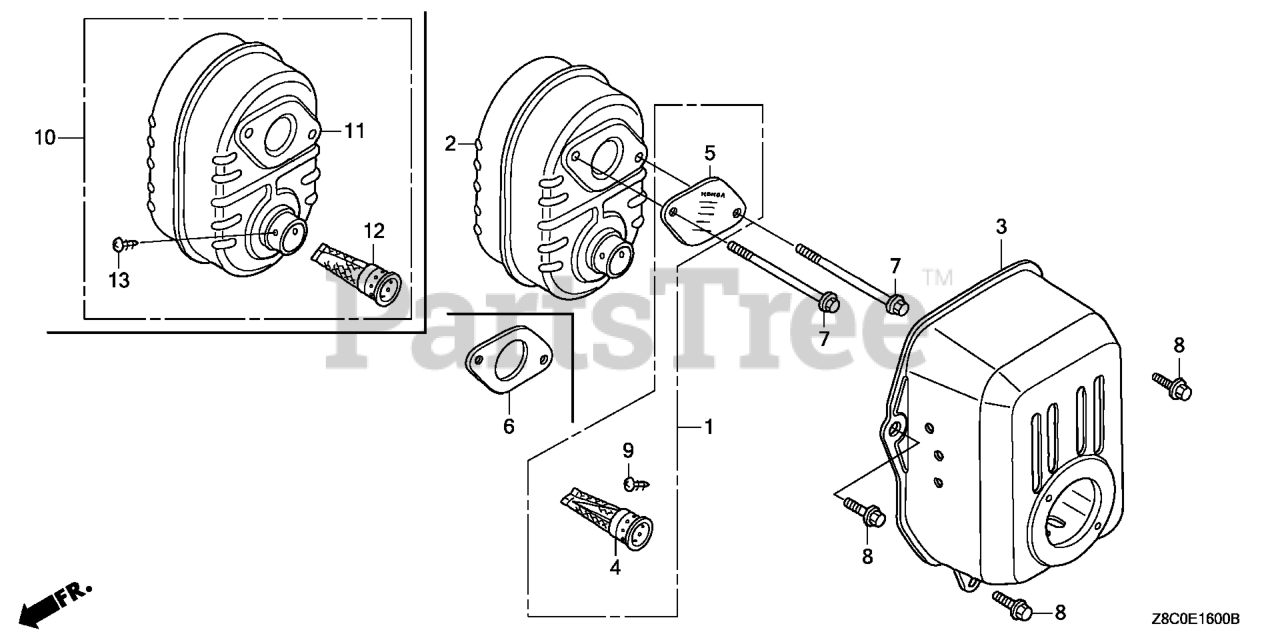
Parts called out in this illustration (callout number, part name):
3	PROTECTOR, MUFFLER
6	GASKET, MUFFLER
7	BOLT, FLANGE (6X79) (CT200)
8	BOLT, FLANGE (6X12) (CT200)
10	MUFFLER ASSY. (ARRESTER)
11	MUFFLER
12	ARRESTER, SPARK
13	SCREW, TAPPING (4X6) (TO INSTALL OPTIONAL SPARK ARRESTER)
